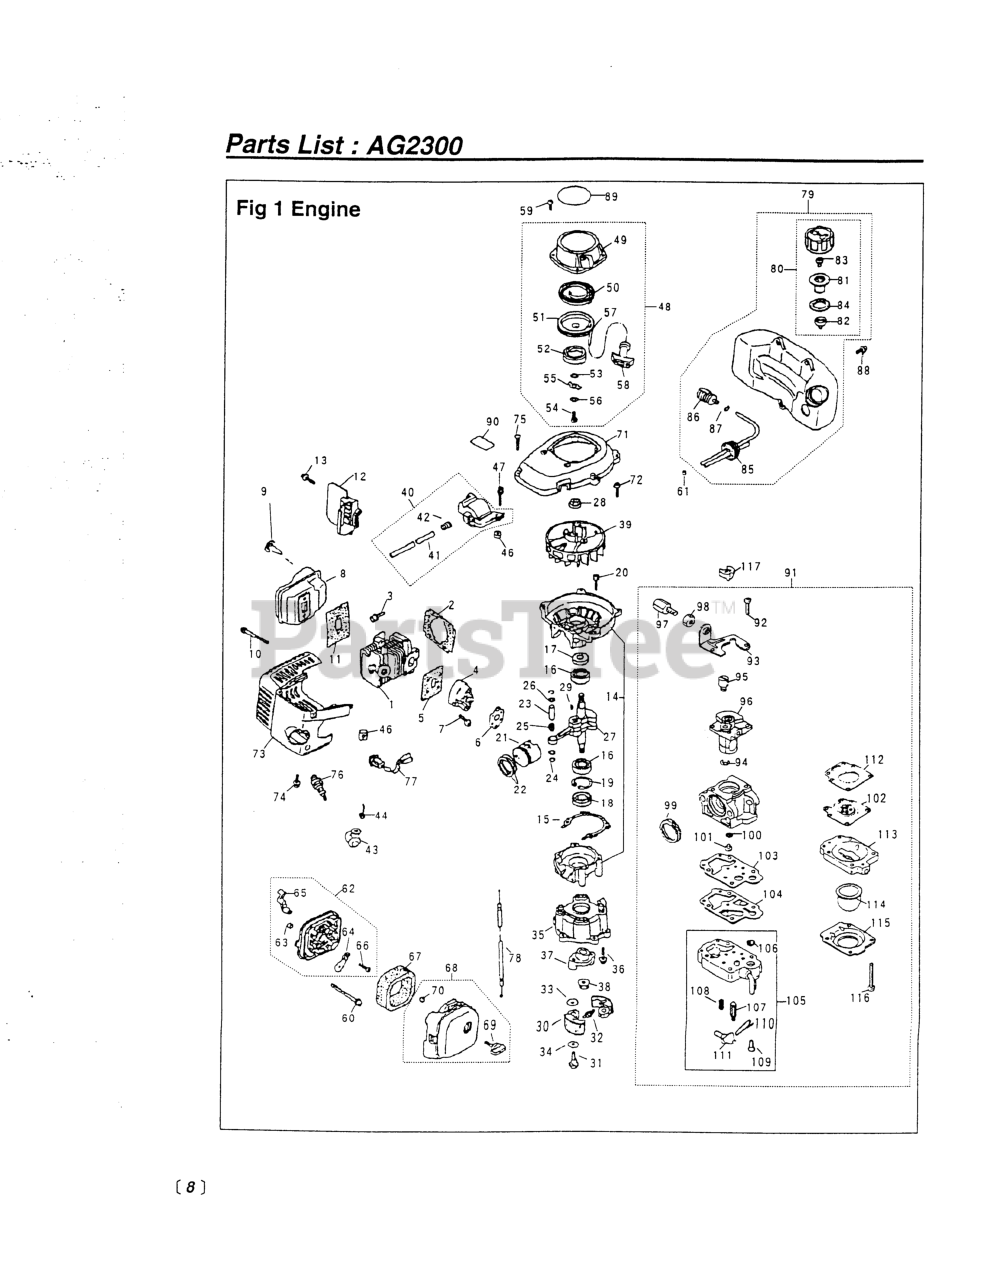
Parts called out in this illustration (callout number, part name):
1	CYLINDER
3	BOLT, M5 X 22
7	SCREW, M5X20 (RPLS.1400-75510)
8	MUFFLER ASSEMBLY
9	ARRESTER (RPLS 5850-15140)
10	BOLT, M5 x 50
11	GASKET, MUFFLER
13	SCREW, M4 X 16
14	CRANKCASE COMP.
16	BEARING
17	SEAL, OIL (RPLS 1100-21210)
18	SEAL, OIL (RPLS 1140-21220)
19	RING, SNAP, M28 x 1.2
20	BOLT, M5 X 30
21	PISTON (REPLACES 1140-41110)
22	RING, PISTON (RPLS 1850-41210)
23	PIN, PISTON 5x8x26
24	RING, SNAP (RPLS 1101-41320)
26	WASHER
27	CRANKSHAFT (RPLS -42000)
29	KEY
31	BOLT
33	WASHER, FLAT (USE 182303)
35	CASE, CLUTCH (USE 1140-21162)
36	SCREW
37	PLATE, CLUTCH
40	COIL ASSY (RPLS 5500-71200)
41	CORD
42	CAP
44	SPRING
46	SPACER (RPLS -71260)
47	BOLT
49	CASE, RECOIL
50	SPRING, SPIRAL
53	WASHER
56	WASHER
57	ROPE
59	SCREW, M4 x 12
60	SCREW, M5 x 60
61	CLIP
62	BODY-A (RPLS -82101)
63	SLEEVE
64	PLATE, CHOKE (RPLS-82130)
65	LEVER, CHOKE
66	SCREW (REPLACES 50030272)
67	ELEMENT
70	RING
71	COVER, FAN
72	SCREW, M5X20 (RPLS.1400-75510)
73	COVER, ENGINE(USE-32101)
74	SCREW, M5 x 12
75	SCREW, HOUSING
77	SWITCH, STOP
78	CABLE
82	HOLDER, CAP
83	VALVE (NLA WHEN OUT)
85	PIPE COMPLETE
86	FILTER ASSY
87	CLIP (REPLACES 2841-31280)
88	SCREW
89	LABEL RECOIL
90	LABEL, FAN COVER
91	CARBURETOR
92	SCREW
94	RING
95	SWIVEL
96	VALVE ASSY
97	SCREW, CABLE ADJUSTER
98	NUT, CABLE ADJUSTER
99	RING, PACKING
100	RING, O
101	JET
102	DIAPHRAGM (USE 4810-81260)
103	GASKET, PUMP
104	DIAPHRAGM
105	BODY, PUMP
107	VALVE, INLET
108	SPRING, METERING LEVER
109	SCREW, METERING LEVER PIN
110	PIN, METERING LEVER
111	LEVER
112	GASKET, DIAPHRAGM
113	BODY, PURGE
114	PUMP, PRIMING
115	COVER, PUMP
116	SCREW
117	WASHER
NI	GROMMET
